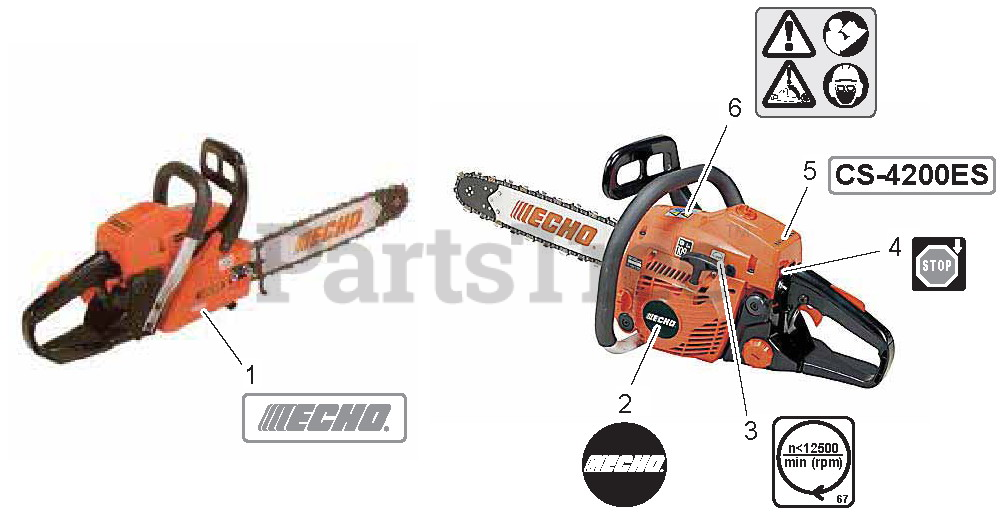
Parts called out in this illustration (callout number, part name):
1	LABEL - ECHO
2	LABEL - ECHO
3	LABEL - CAUTION
4	LABEL - STOP
5	LABEL - MODEL CS-4200ES
6	LABEL - CAUTION
